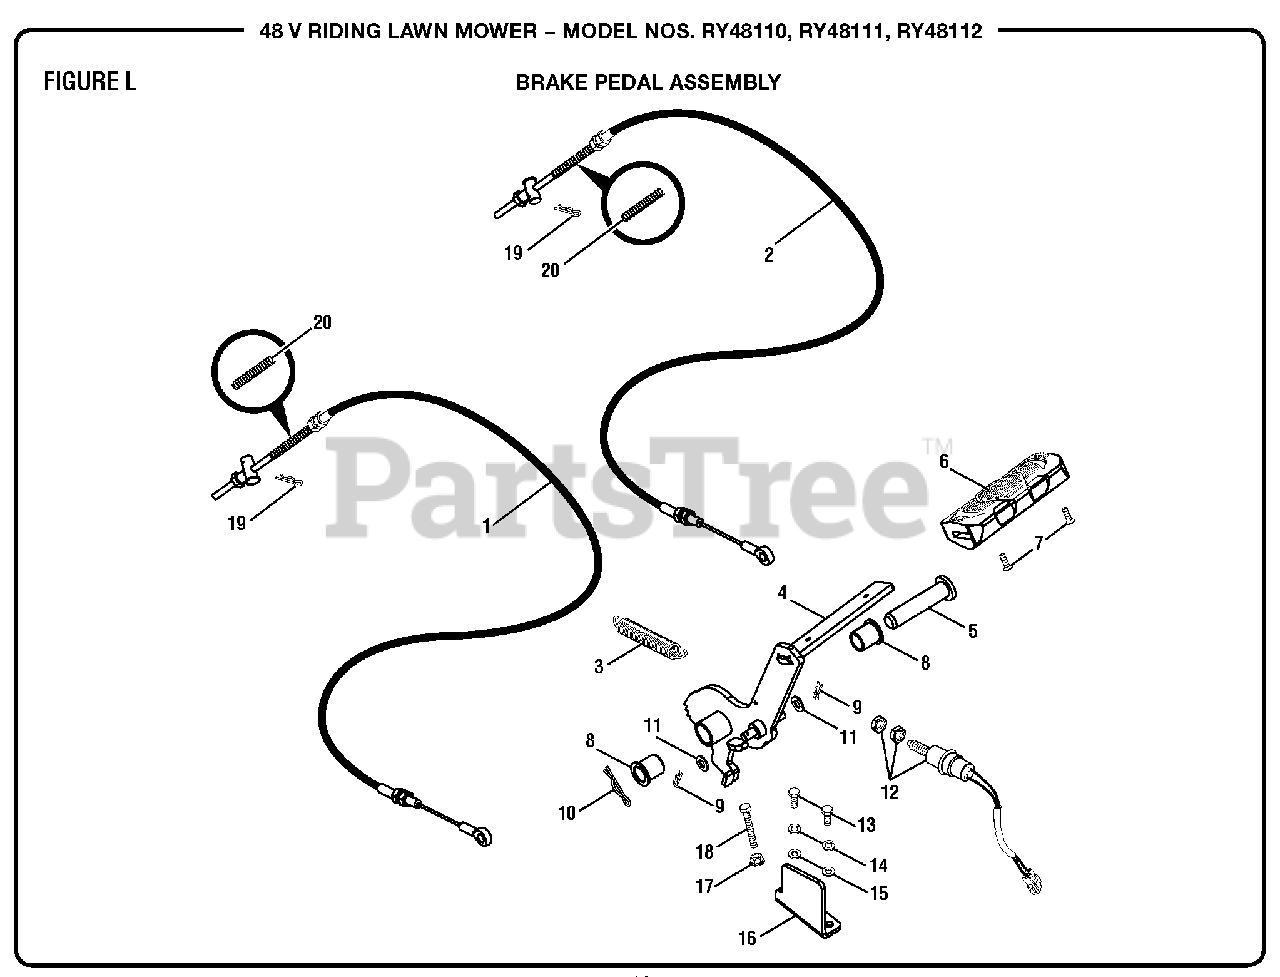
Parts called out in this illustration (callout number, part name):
1	Right Brake Cable
2	Left Brake Cable
3	Pedal Spring
5	Clevis Pin
6	Brake Pedal
7	Screw (M5 x 16 mm, Flat Hd.)
9	Lock Pin (8 mm)
10	Lock Pin (16 mm)
11	Washer (OD16 x ID8.4 x 1.6t)
12	Brake Switch Assembly
13	Bolt (M6 x 16 mm, Hex Hd.)
14	Spring Washer (M6)
15	Washer (OD12 x ID6.4 x 1.6t)
16	Brake Switch Guard
17	Flange Nut (M6)
18	Bolt (M6 x 45 mm, Hex Hd.)
20	Compression Spring
